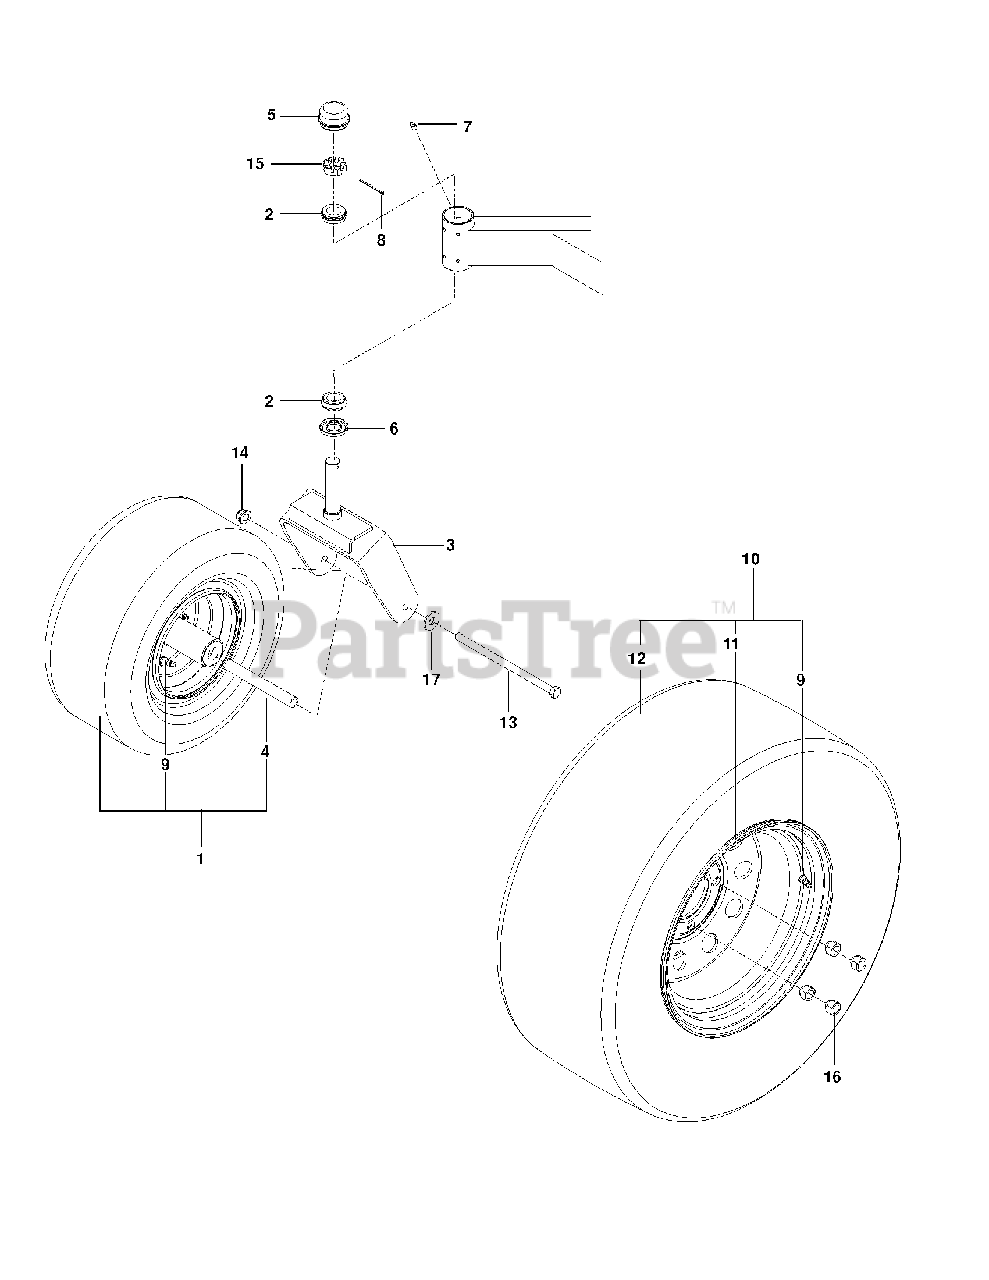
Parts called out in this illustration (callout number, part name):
2	TAPERED ROLLER BRG
3	YOKE, CASTER, BLUE
4	SPACER, PIVOT
5	GREASE CAP
9	VALVE STEM TR-412
10	TIRE 23X8.5-12
11	RIM 12X7 .236 NEG OFFSET
12	TIRE - 23X8.5-12
13	HEX SCREW 1/2-13 X 9.5 GR5
14	NUT, 1/2-13 HEX FLG NYLOC ZD
15	NUT 1"C HEX SLOTTED
16	LUG NUT 1/2F
17	WASH USS FLAT 1/2
